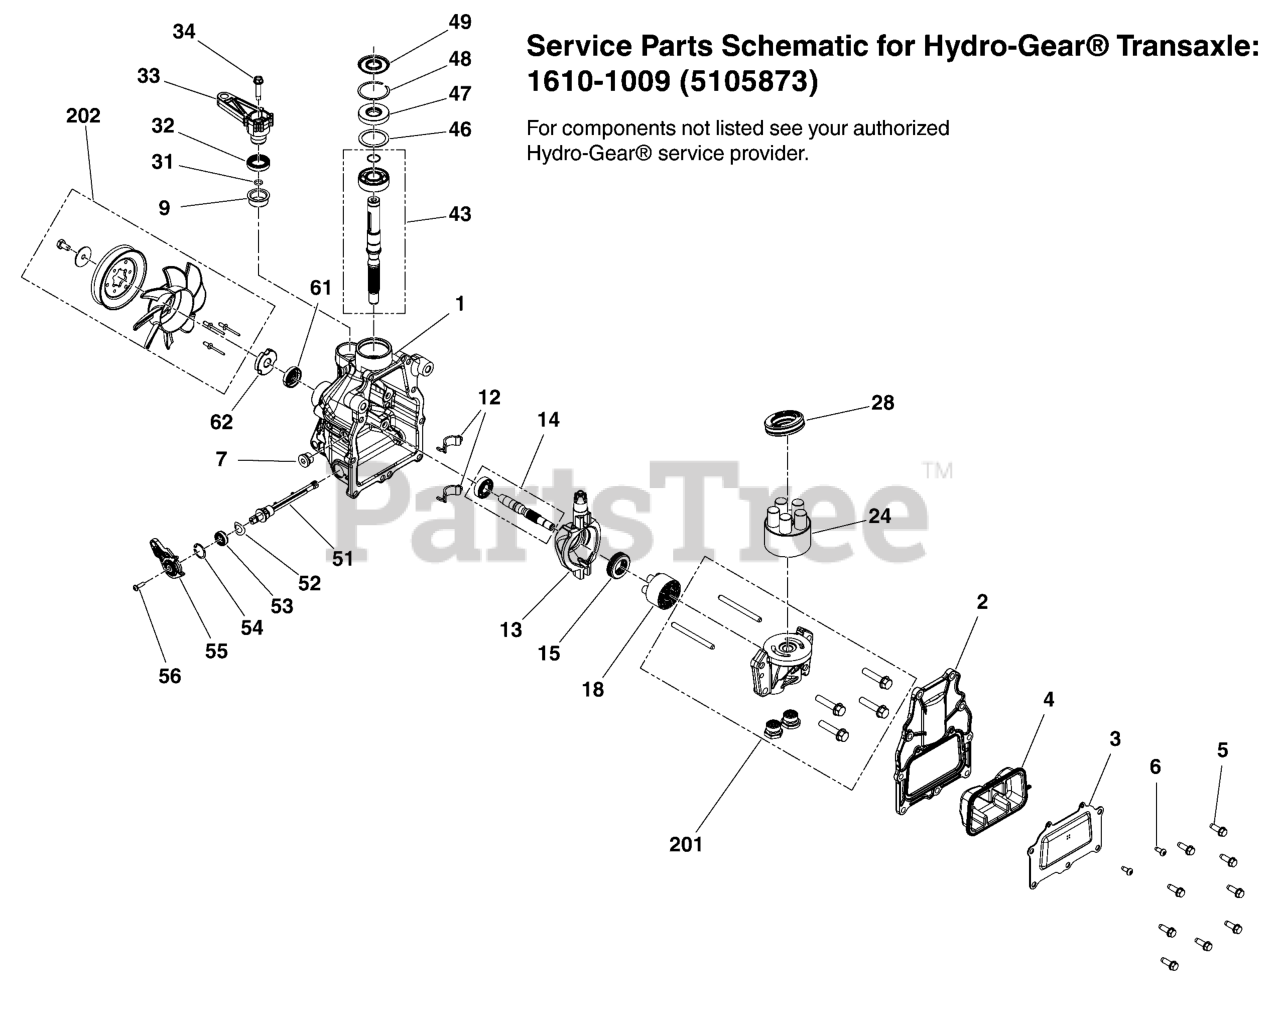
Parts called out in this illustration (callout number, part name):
1	HOUSING, MAIN
2	COVER
3	PLATE, EXPANSION
4	BLADDER
6	BOLT, SELF-TAPPING
7	PLUG, 9/16-18 STR THREAD SOCKET HEAD
9	GUIDE, PLASTIC ALIGNMENT
12	BEARING, CRADLE
13	SWASH_PLATE
14	KIT, INPUT SHAFT
18	KIT, 3cc BLOCK
24	KIT, BLOCK 10cc CYLINDER
33	ARM, CONTROL
43	KIT, MOTOR SHAFT
46	SPACER (50951)
47	OUTPUT SHAFT SEAL, 17X40X7, HR #51161
48	RING, M40, RET, INT
49	SLEEVE, SEAL GUARD
51	ACTUATOR, BYPASS
52	WASHER, .45 X .73 X .01, SPRING
53	SEAL, .375 X .750 X .25 LIP, H/G 51626
55	ARM, BYPASS
56	SCREW, M4 X 16, WUPLAST
200	KIT, SEAL
201	KIT, CENTER SECTION
202	KIT, FAN/PULLEY
